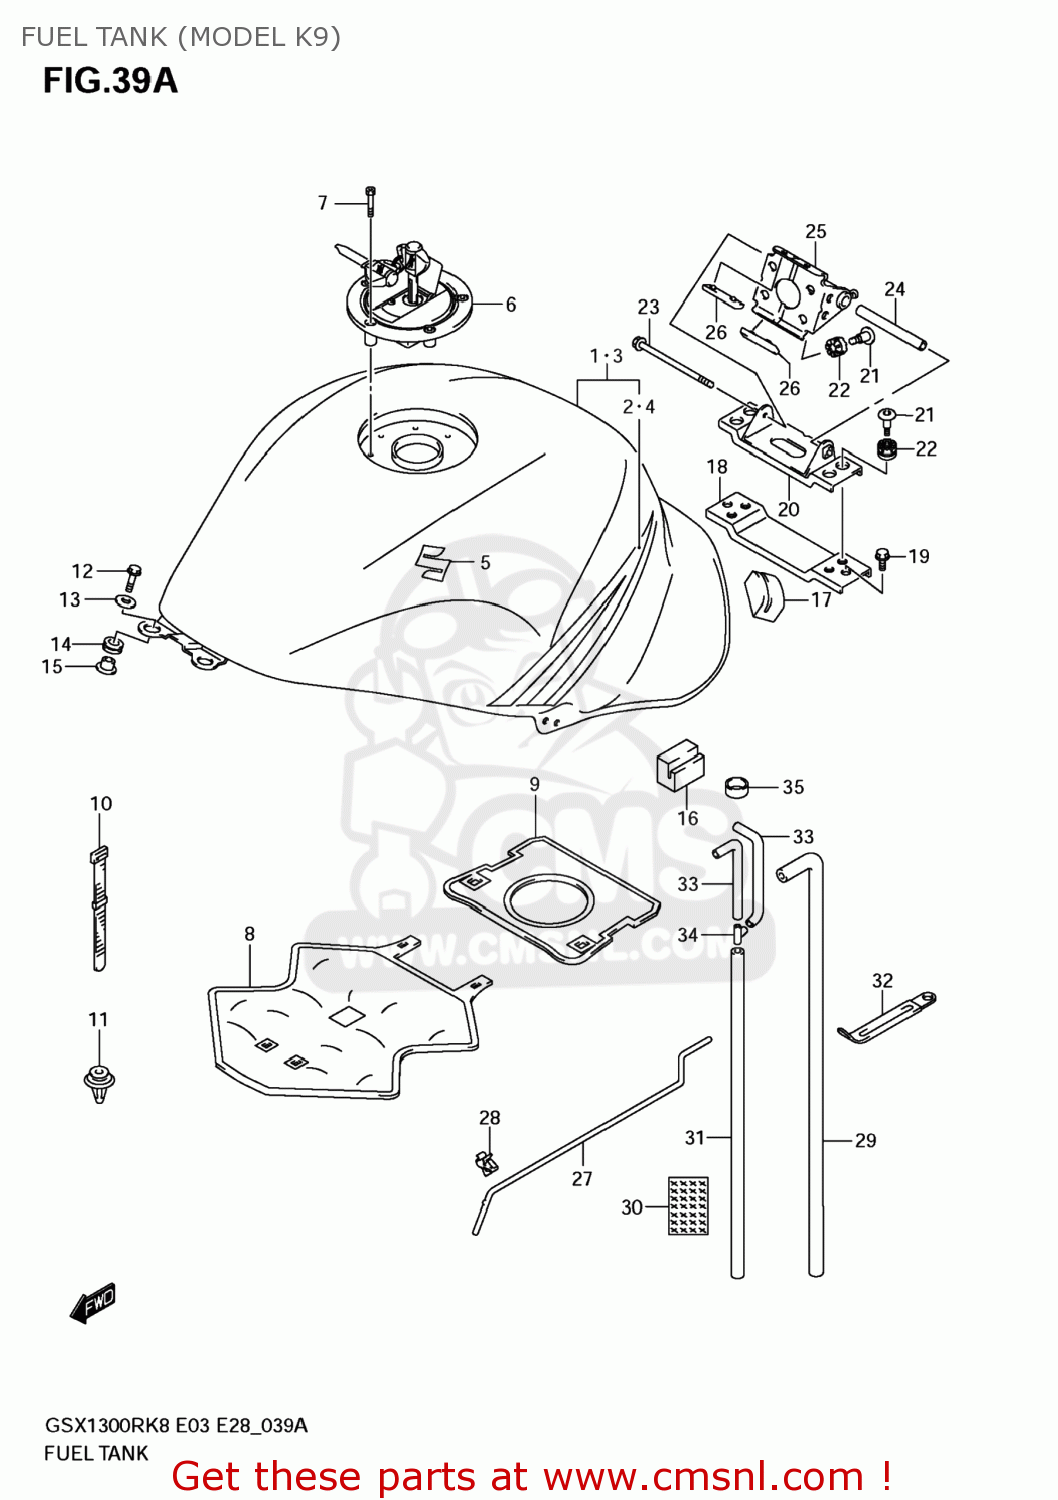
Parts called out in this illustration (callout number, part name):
1	TANK ASSY,FUEL(BLACK)
2	TAPE SET,FUEL TANK
3	TANK ASSY,FUEL
4	TAPE SET,FUEL TANK
5	EMBLEM,S
6	CAP SET,FUEL TANK
7	BOLT(5X20)
8	SHIELD,FUEL TANK HEAT NO.1
9	SHIELD,FUEL TANK HEAT NO.2
10	CLAMP(L:165)
11	CLIP
12	SCREW(6X25)
13	WASHER(6.5X22X1.6)
14	CUSHION,FUEL TANK FR
15	SPACER,FUEL TANK FR
16	CUSHION,FUEL TANK SIDE
17	CUSHION,FUEL TANK RR
18	BRACKET,FUEL TANK RR NO.3
19	BOLT
20	BRACKET,FUEL TANK RR NO.2
21	SCREW,FUEL TAN
22	CUSHION
23	BOLT
24	SPACER,FUEL TANK RR
25	STEUN.BENZ.TANK
26	CUSHION,SEAT FR
27	STAY,FUEL TANK
28	CLAMP
29	HOSE,FUEL TANK DRAIN
30	SHIELD,DRAIN HOSE HEAT
31	HOSE,FUEL TANK BREATHER
32	CLAMP(L:65)
33	HOSE,TANK BREATHER NO.2
34	3 WAY
35	HOSE(12X16X600)
